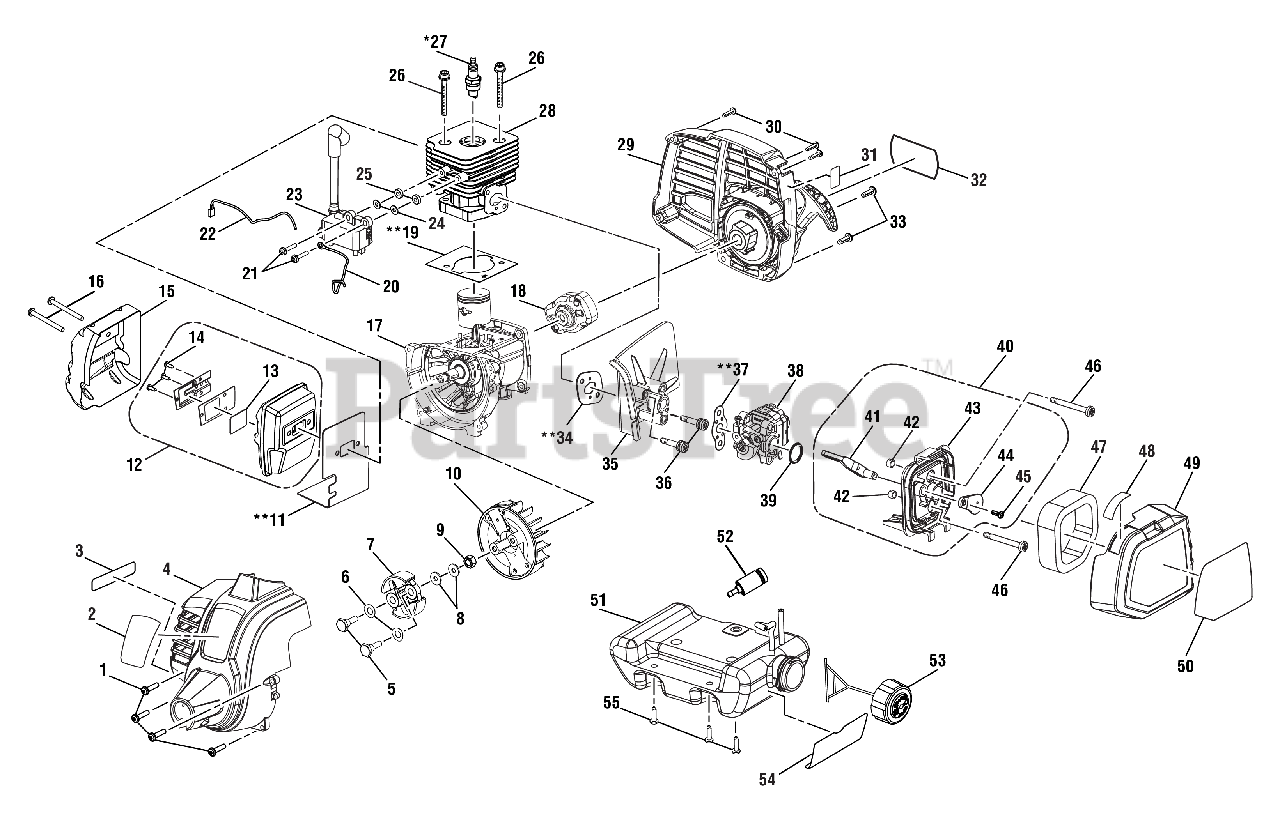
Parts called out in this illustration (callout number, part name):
1	Cap Screw w/Washer (M5 x 16 mm, T25 Torx Soc. Hd.)
2	Logo Label (Front)
3	Warning Label (Combustion)
4	Front Housing Assembly w/ Labels
5	Clutch Shoulder Bolt (M6 x 22.5 mm, Hex Hd.)
6	Washer (Curved)
7	Clutch Assembly
8	Washer (ID6 x OD15 x 1.2t)
9	Flange Nut (M8, Flywheel)
11	Muffler Gasket
12	Muffler Assembly
13	SCREEN
14	Screw (6-20 x 1/4 in., T20 Torx Pan Hd. S.T.)
15	HEAT SHIELD
16	Screw (M5 x 50 mm, Torx Slotted Recessed Pan Hd.)
17	Crankcase Assembly
18	Starter Cup
19	Gasket
20	Lead Wire Assembly, Red
21	Screw w/Washer (M4 x 19 mm, T20 Torx Pan Hd. S.T.)
22	Lead Wire Assembly, Black
23	Coil Boot Assembly
24	Flat Washer (OD10 x ID42 x 1t)
25	Phenolic Spacer (Ignition Module)
26	Screw (M5 x 22 mm, T25 Torx Soc. Hd.)
27	Spark Plug (Champion RCJ6Y)
29	Screw (M4 x 18 mm, T20 Torx Pan Hd. S.T.)
30	Screw (M4 x 20 mm, T20 Torx Pan Hd. S.T.)
31	Primer Bulb Location Label
32	Shoulder Screw (M4 x 14 mm, T25 Torx Truss Hd.
33	Cap Screw w/Washer (M5 x 16 mm, T25 Torx Soc. Hd.)
34	Heat Dam Insulator
35	Screw (M5 x 30 mm, T25 Torx Pan Hd. S.T.)
36	Screw (M5 x 27 mm, T25 Torx Pan Hd. S.T.)
37	Gasket
38	Carburetor Assembly
39	Carburetor O-Ring
40	Airbox Base Assembly
41	Compression Limiters
42	Washer (ID5.8 x OD11.5 x 1.7t)
43	Air Box Base
44	Screw (M4 x 12 mm, T20 Torx Pan Hd. S.T.)
45	Screw (M4 x 12 mm, Slotted Recessed Pan Hd.)
46	Screw (M5 x 44 mm,T25 Torx Hd. Carburetor)
47	Air Filter (Element)
48	Choke Position Label
49	Airbox Cover (Inc. Key Nos. 48 & 50)
50	Starting Instructions Label
51	Fuel Tank and Cap Assembly
52	Fuel Filter
53	Fuel Cap Assembly
54	Fuel Mixture Label
55	Shoulder Screw w/Washer (M4 x 14 mm, T25 Torx Truss Hd.)
